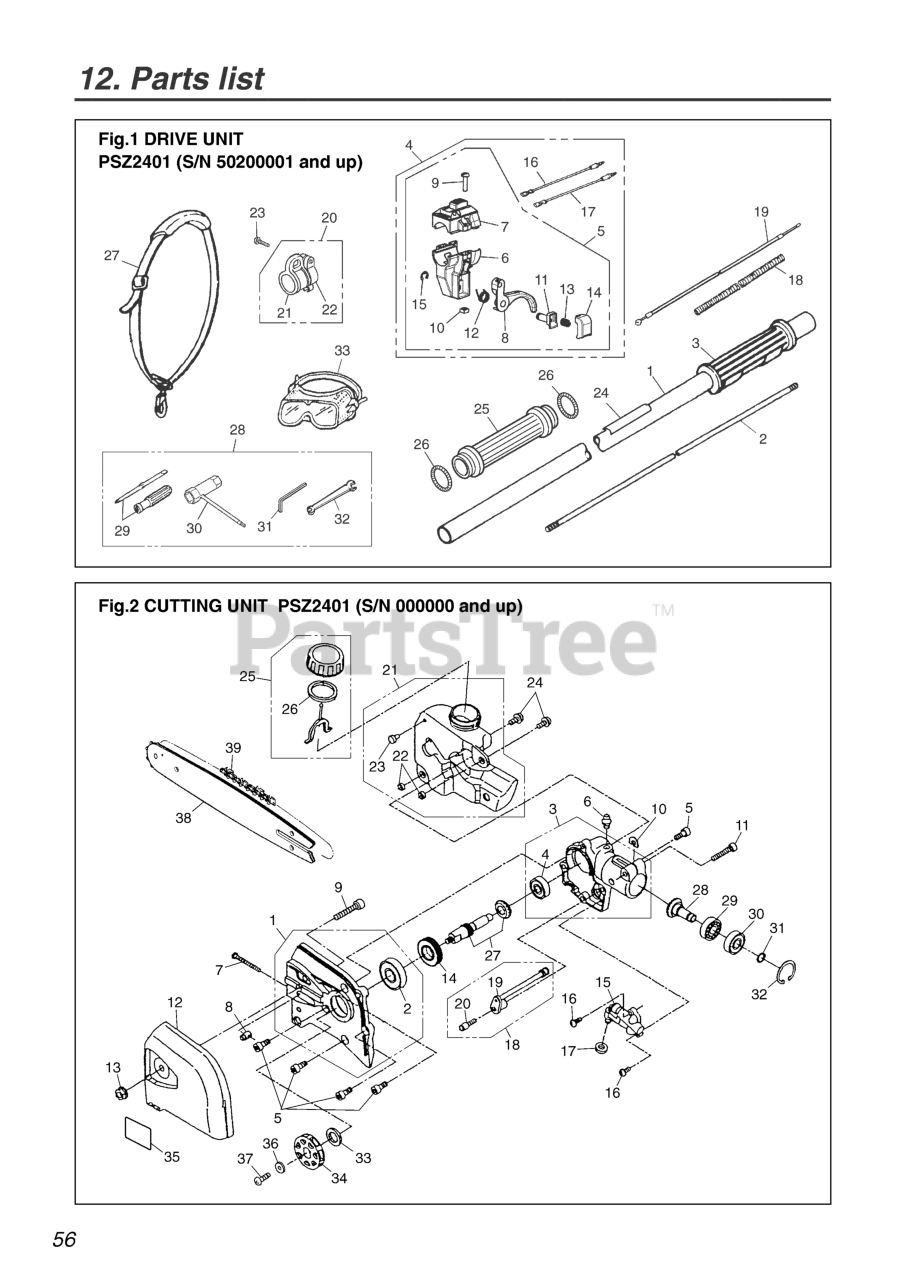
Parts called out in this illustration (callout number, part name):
1	PIPE COMP.
2	SHAFT (RPLS -12212)
3	GRIP (RPLS 3577-32140 & 3220-
4	LEVER ASSY. (RPLS. T3002-12203
5	LEVER ASSY (RPLS. 6110-14412)
7	COVER (USE 848-8RA-0340)
8	FLEX, TRIGGER
16	CORD (A), BLACK
17	CORD (B), RED
18	TUBE (RPLS 4900-72141)
19	CABLE (RPLS 5580-83100)
20	HANGER COMP.
23	SCREW
24	NAME PLATE
25	GRIP
26	SPRING
27	STRAP ASSY.
28	TOOL-SET
29	SCREWDRIVER
31	WRENCH (TOOL)
32	SPANNER, 8 X 10 (RPLS 2540- )
33	GOGGLE
A2	BEARING
A3	GEARCASE COMP (RIGHT)
A5	BOLT, M5 x 12
A6	FITTING, GREASE
A7	SCREW
A8	NUT
A9	BOLT, M6 x 30
A10	SHIM
A12	COVER, CHAIN
A13	NUT
A14	GEAR, WORM
A15	PUMP ASSY, OIL
A16	SCREW, M4 x 10
A17	GASKET
A18	PIPE ASSY, OIL
A19	PIPE, OIL
A20	FILTER
A21	TANK ASSY, OIL
A22	COLLAR
A23	VALVE
A24	SCREW, M5 X 12
A25	CAP ASSY, OIL
A26	GASKET, OIL CAP
A27	SHAFT, GEAR
A28	GEAR, BEVEL
A29	BEARING (RPLS T3403-13530)
A31	RING, SNAP (RPLS T3300-13330)
A32	RING, SNAP, M24 x 1.2
A33	COLLAR
A34	SPROCKET
A35	LABEL (PSZ2500)
A36	WASHER
A37	SCREW
A38	12
A39	12
